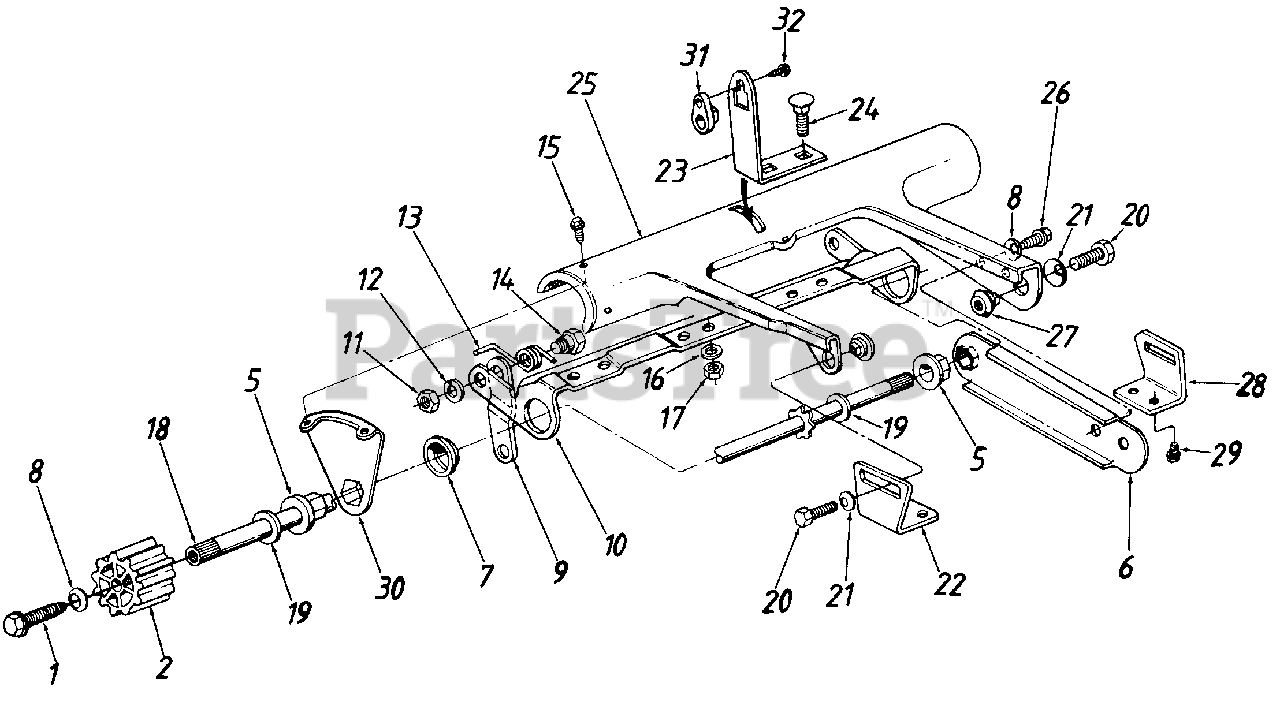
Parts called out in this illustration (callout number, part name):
1	Hex Wash. Hd. Tap Scr. 1/4-20 x .75" Lg.
2	Wheel Drive Pinion-Half
5	Hex Flange Brg. .504" I.D.
8	Bell-Wash. .265" I.D. x .75" O.D.
9	Link 4.58" Lg.
10	Drive Engagement Cam
11	Hex Nut 5/16-18 Thd.
12	L-Wash. 5/16" I.D.
13	Torsion Spring-R.H.
14	Shoulder Bolt .437" Dia.
15	Hex AB-Tap Scr. 1/4" x .62" Lg.
16	L-Wash. 1/4" I.D.
17	Hex Nut 1/4-20 Thd.
18	Drive Shaft Ass'y.
19	Fl-Wash. .531" I.D. x .93" O.D.
20	Hex Bolt 5/16-18 x .50" Lg.
21	Bell-Wash. .345" I.D. x .88" O.D.
22	Pivot Bracket-R.H.
27	Shoulder Nut
28	Pivot Bracket-L.H.
29	Hex Wash. Hd. AB-Tap Scr. 1/4 x.62" Lg.
32	Hex B-Tap Scr. #10 x .44" Lg.
